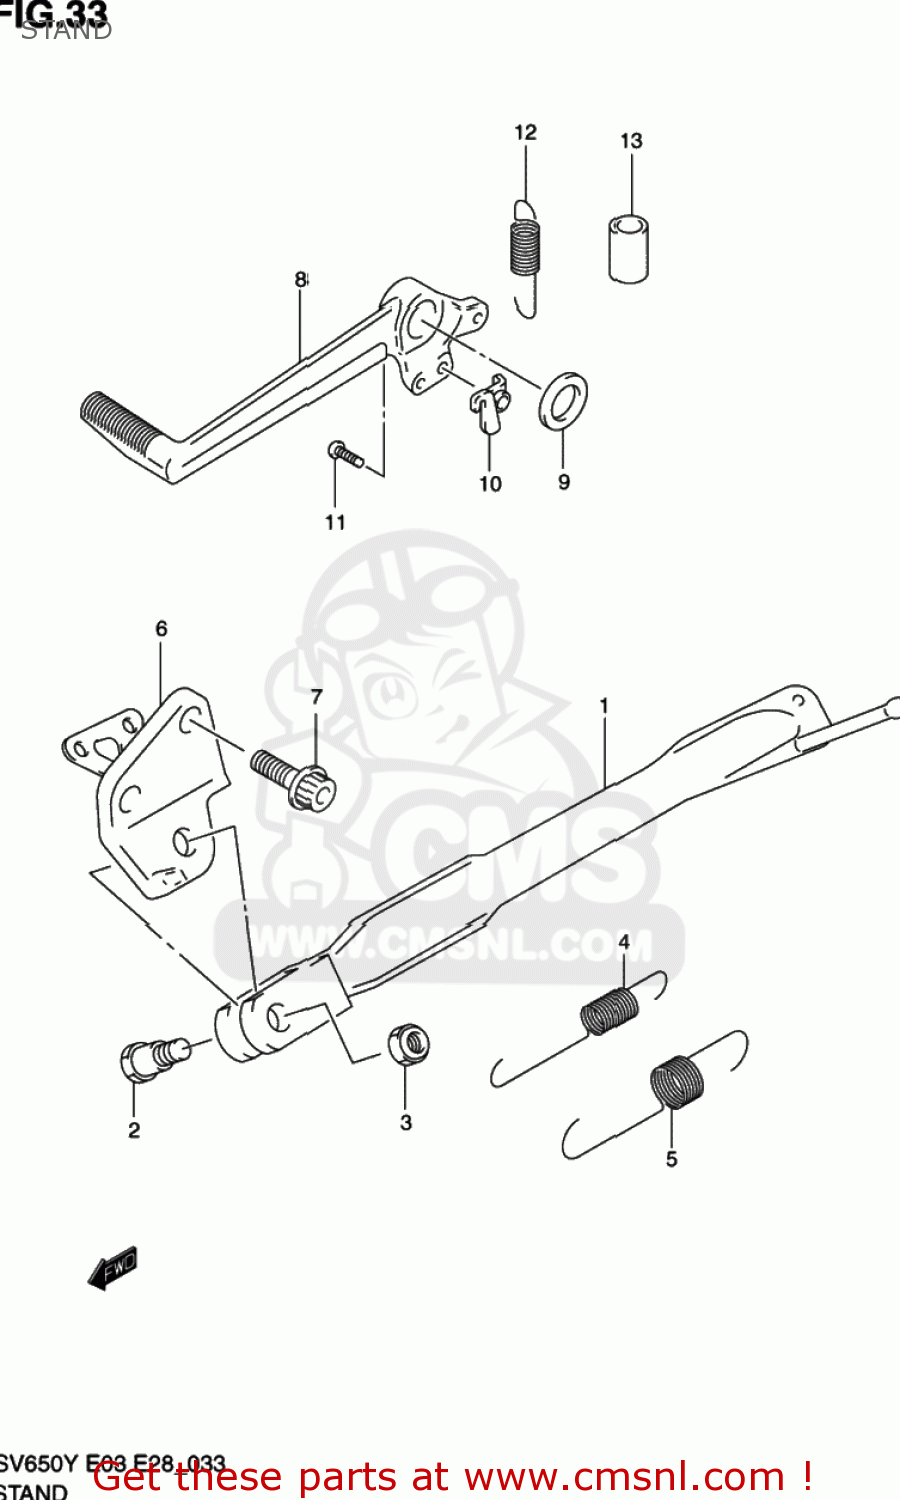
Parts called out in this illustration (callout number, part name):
1	STAND,PROP
2	BOLT(10X34)
3	NUT
4	SPRING
5	SPRING
6	BRACKET,PROP STAND
7	BOLT
8	PEDAL,BRAKE
9	WASHER(18X24X1)
10	HOOK,RETURN SPRING
11	SCREW
12	SPRING
13	TUBE,BRAKE SPRING GUIDE
